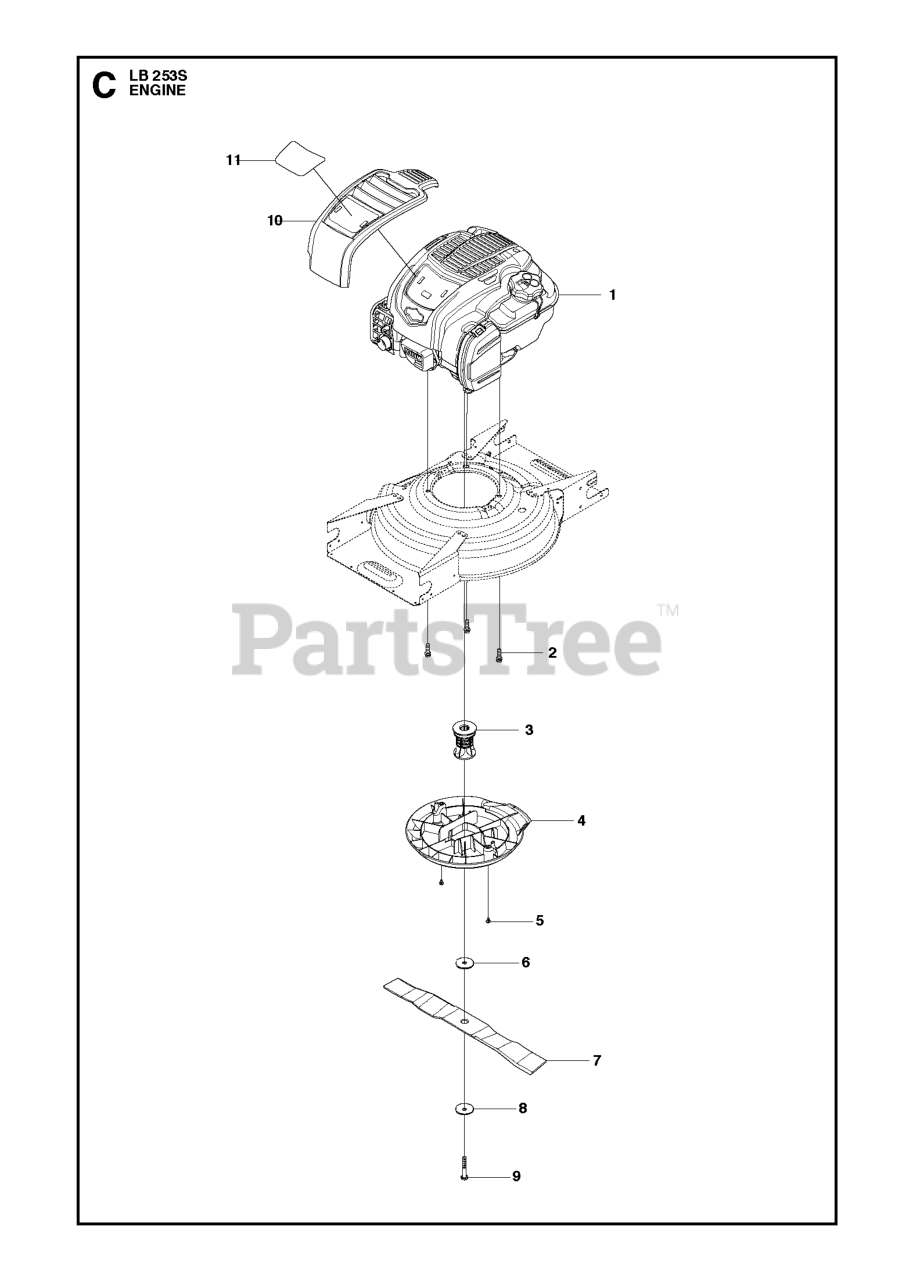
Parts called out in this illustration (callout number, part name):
2	BOLT 3/8-16X1-1/8
4	BELT COVER A009-2
5	SCREW ITXPANTT M5X10 ZPB (A00
